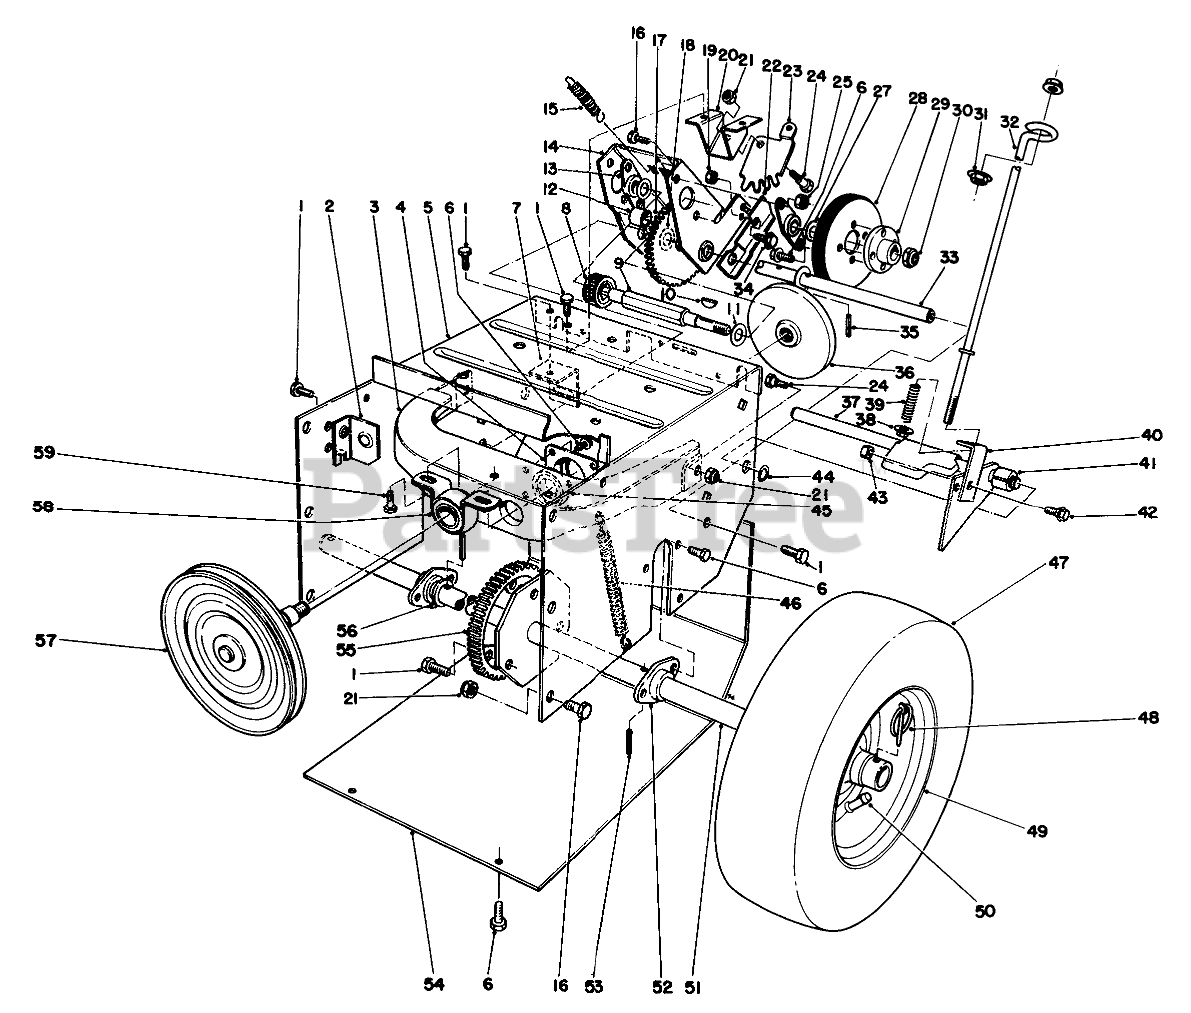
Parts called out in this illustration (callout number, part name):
1	SCREW-HWHTF
2	AUGER CLUTCH MTG FRT
3	"OBS" FRICTION PLT FRAME
4	CUP-BEARING
5	Frame-Traction
6	SCREW-HWH
7	BRACKET-MOUNT, REAR
8	PINION
9	SHAFT-WHEEL, FRICTION
10	KEY-WOODRUFF
11	WASHER-FLAT
12	5/8ID X 1LG BUSHING
13	BEARING-WHEEL, FRICTION
14	BRACKET-SLIDING
15	SPRING-TRACTION
16	SCREW-HH
17	Intermediate Gear & Bushing (Incl. Ref. #12)
18	WASHER-SPECIAL
19	NUT-LOCK, NI
20	MOUNT-LEVER
21	NUT-LOCK, NI
22	CAM-RECEIVER
23	GEAR-QUADRANT
24	BOLT-SHOULDER
25	NUT-LOCK, CONE
27	WASHER-THRUST
28	WHEEL-FRICTION
29	HUB-WHEEL, FRICTION
30	NUT-LOCK, NI
31	NUT-HF
32	ROD-TRACTION, LOWER
33	SHAFT-PIVOT
34	SCREW-HH
35	PIN-SPRING
36	PLATE-FRICTION
37	Traction Engagement Asm.
38	NUT-HHF
39	SPRING
40	BRACKET-TRACTION
41	SPACER
42	SCREW
43	NUT-LOCK, NI
44	RING-RETAINING
45	BEARING-BALL
46	SPRING-PLATE, FRICTION
48	PIN-LYNCH
49	WHEEL
51	AXLE SHAFT WA
52	BEARING-AXLE
53	PIN-SPRING
54	Bottom Cover
55	GEAR-AXLE
56	WASHER-THRUST
57	Pulley & Shaft
58	BUSHING ASM
59	SCREW-HWHTF
